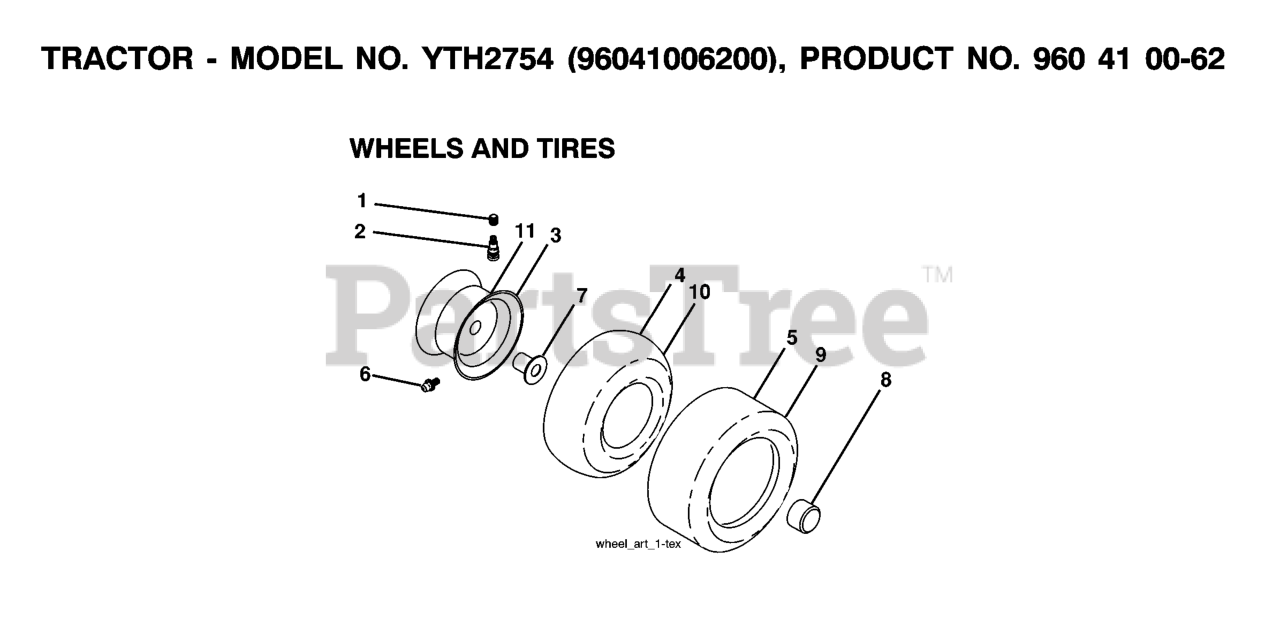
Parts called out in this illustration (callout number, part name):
2	VALVE STEM LT
3	RIM ASSEMBLY, FRONT
4	TUBE.5.3/4.5/6
5	TIRE HEAVY DUTY
6	FITTING LT
7	BEARING T
8	CAP, AXLE BLK
9	TIRE.22X9.50-12.TURF.SAVER.REA
10	TUBE
11	RIM.ASM.12".REAR.SILVER
